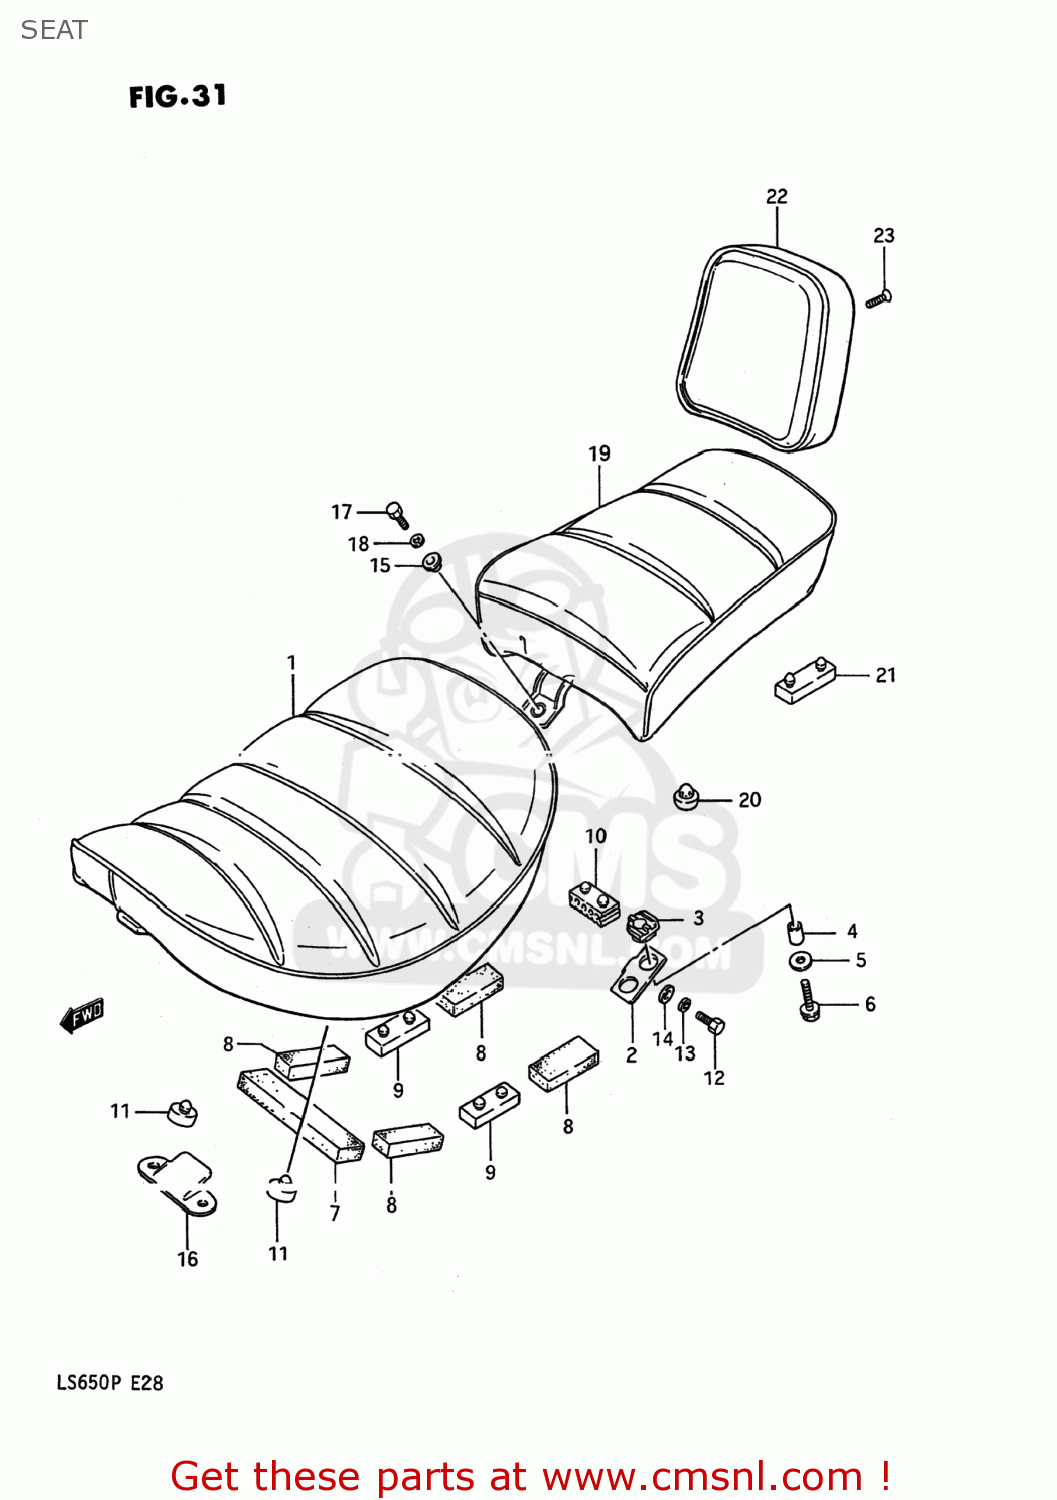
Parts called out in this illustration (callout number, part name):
1	SEAT SET
2	BRACKET,SEAT RR
3	CUSHION,SEAT RR BRACKET
4	COLLAR,SEAT(TS-5A1-02273)
5	WASHER
6	BOLT
7	CUSHION,CTR FR
8	CUSHION,CTR SIDE
9	CUSHION,SEAT
10	CUSHION,SEAT(40X20X15)
11	CUSHION,FR
12	SCREW
13	WASHER,LOCK
14	WASHER
15	WASHER
16	PLATE,SEAT HOOK FR
17	BOLT
18	WASHER,LOCK
19	SEAT SET,PILLION
20	CUSHION,SEAT
21	CUSHION,SEAT
22	PAD ASSY,SEAT
23	SCREW
